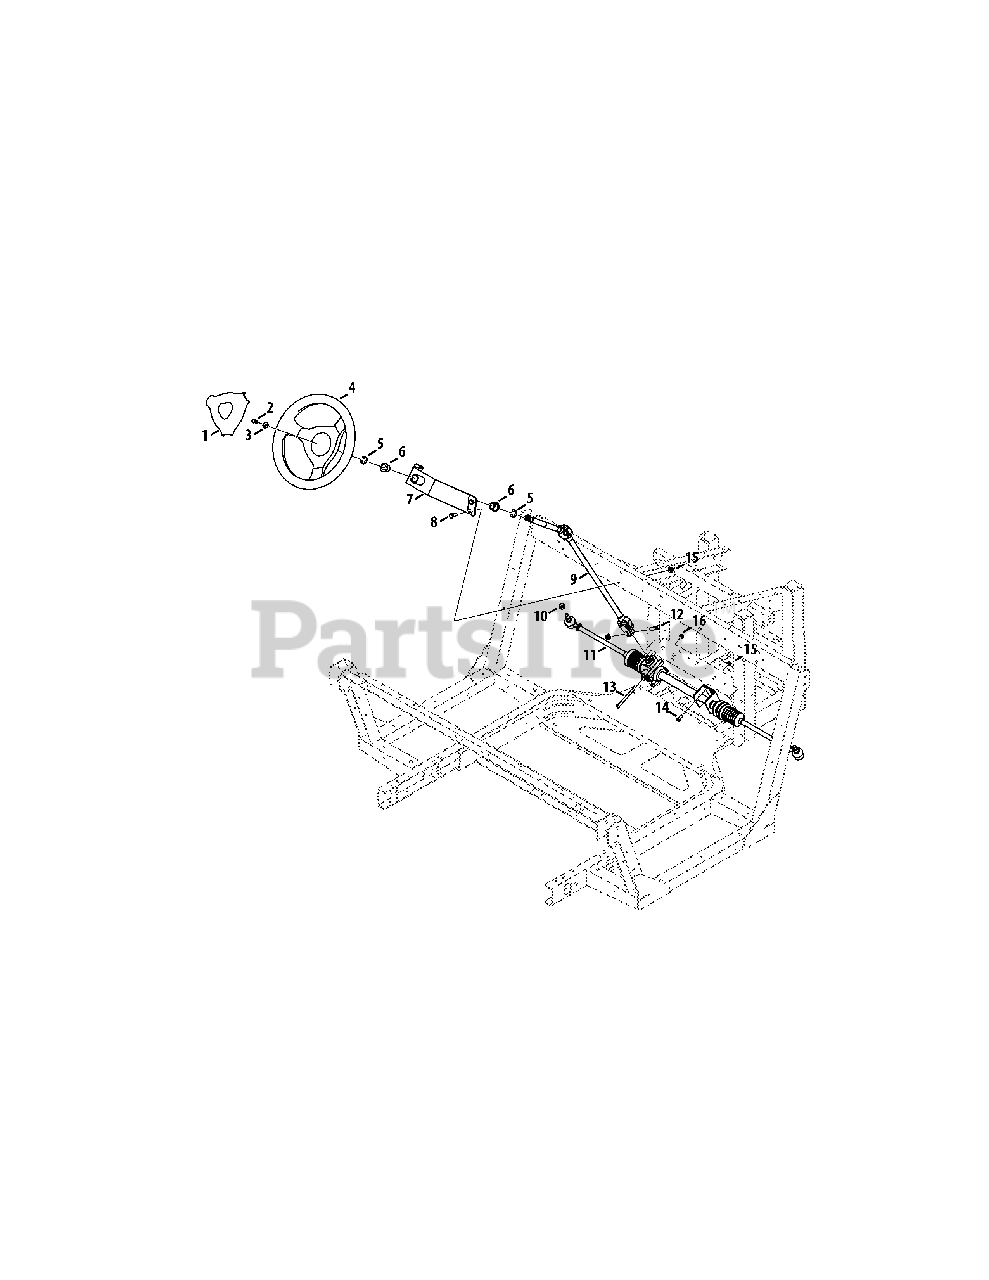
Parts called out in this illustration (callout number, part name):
1	Cover, Steering Wheel
2	Screw, 5/16-18 x .75, gr5, patch
2	Screw, 5/16-18 x 1.00, gr5, patch
3	Washer, bell, .340 x .872 x .060
4	Steering Wheel, Soft Grip 3 Spoke 5/8
5	Ring, e Type, .750
6	Flange Bearing, .754id x 1.00od x.925
8	Screw, 3/8-16 x 1.00, gr5, std
9	Shaft, Steering
10	Nut, Nylock, m12 x 1.25
11	Steering Assembly
12	Screw, 3/8-16 x 1.25, gr5, std
13	Screw, 5/16-18 x 3.50, gr5, std
14	Screw, 5/16-18 x .75, gr5, std
15	Nut, Flange Lock, 3/8-16, Nylon
16	Nut, Flange Lock, 5/16-18
